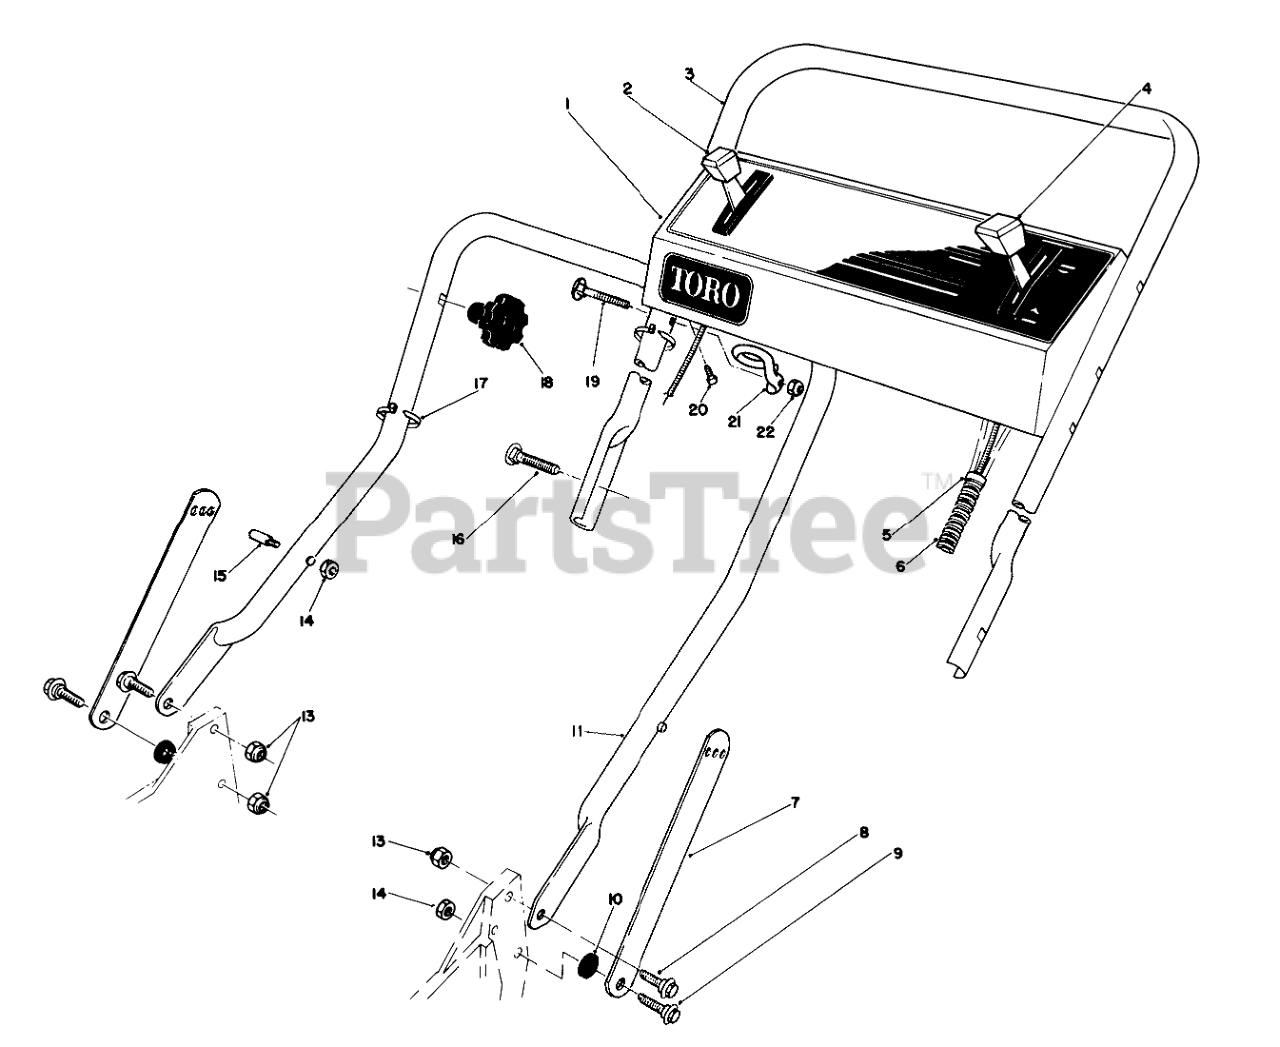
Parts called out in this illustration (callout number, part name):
1	CONTROL PANEL
2	GROUND SPEED CONTROL
3	UPPER HANDLE
4	THROTTLE CONTROL
5	FITTING-RING
6	CONTROL CABLE COVER
7	Handle Latch
8	SCREW-SHOULDER
9	SCREW-SHOULDER
10	SPACER
11	LOWER HANDLE ASM
13	NUT-LOCK, NI
14	NUT-LOCK, NI
15	HANDLE PIN
16	5/16-18 X 2 HNDLE SCREW
17	TIE-CABLE
19	HANDLE SCREW
20	SCREW-HWHTF
21	Guide
22	NUT-LOCK, NI
